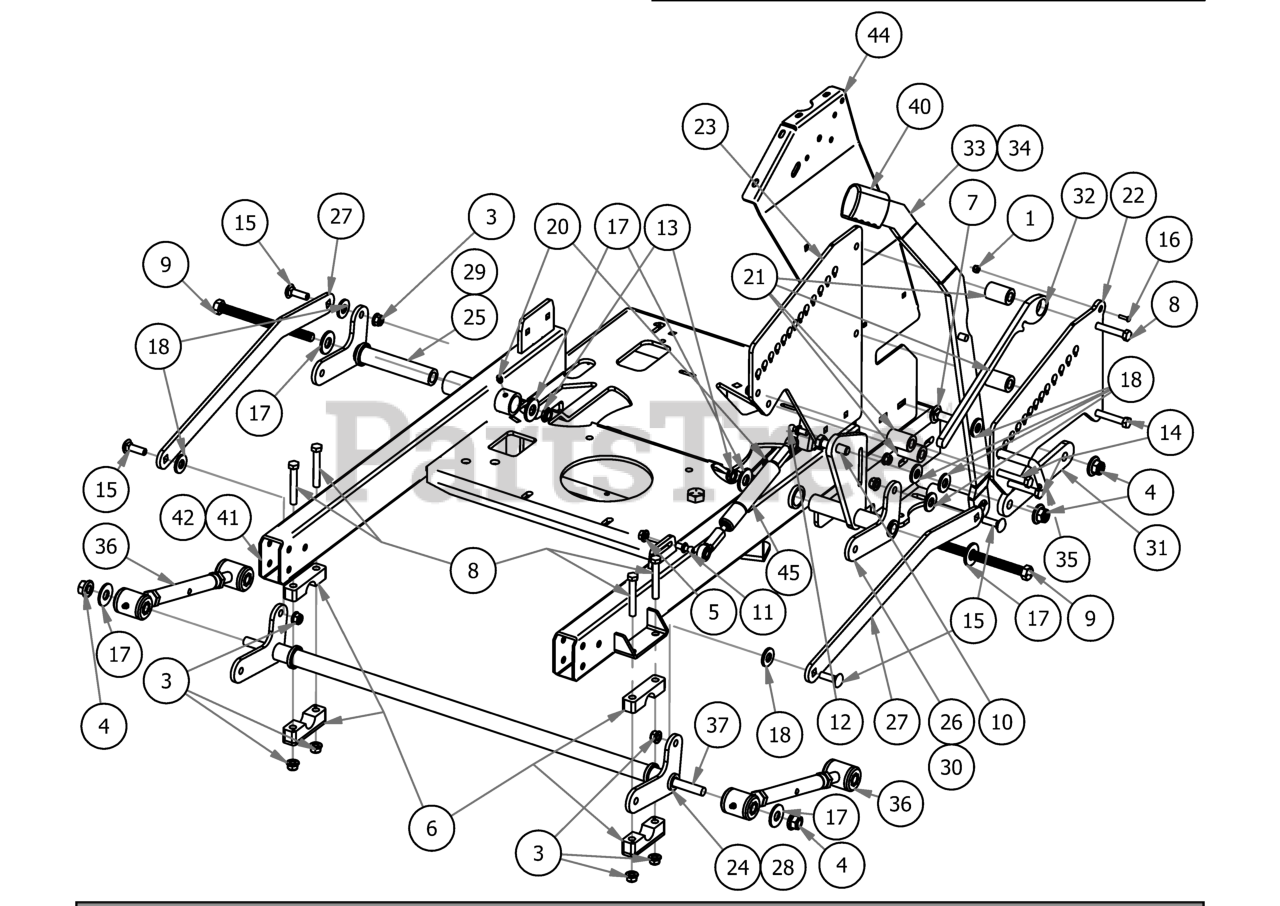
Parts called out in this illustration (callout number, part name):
1	10-24 Nylon Insert Locknut Zinc
2	3/8 Nylock Nut
3	3/8 Nylock Flange Nut
4	1/2-13 NYLON INSERT FLANGE LOCKNUT ZINC
5	5/16-18 Hex Flange Nuts Zinc w
6	Pillow Block Kit
7	1/2-13 X 1-1/2 CARRIAGE BOLT (GR.5) ZINC
8	3/8-16 x 2 1/2" Hex Bolt
9	1/2-13 x 6 1/2 Hex Bolt
10	1/2-13 x 1 3/4" GR5 Hex Bolt
11	10mm Damper Ball Stud-Steering
12	10mm Damper Ball Stud-XP Linkage
13	1/2-13 NYLON INSERT JAM LOCKNUT ZINC
14	3/8-16x3 grade 5 hex bolt
15	3/8-16 X 1-1/4 Carriage Bolt
16	10-24 X 5/8 BS C/S 18-8 SS
17	1/2 Flat Washer
18	.505 Nylon Spacer
19	Revolt Cotter Pin for 7/8" to 1" shank
20	1/4" Press in Grease Fitting
21	.502 ID X .750 OD X 1.500 Long Spacer
22	2019 Stand On Outer Adjustment Plate
23	2019 Stand On Inner Adjustment Plate
24	2019 Stand On Front Actuator Bar Weldment
25	2019 Stand On Actuator Bar Rear RH
26	2019 Stand On Actuator Bar Rear- LH
27	2019 Stand-on Actuator Linkage
28	2020 36 Stand On Front Actuator Bar Weldment
29	2020 36 Stand On Actuator Rear RH
30	2020 36 Actuator rear_LH
31	2019 Stand On Lever Secondary Linkage
32	2019 Stand on deck lever lock
33	2019 Stand On Lift Lever Weldment
34	2020 36 Stand On Lift Lever Weldment
35	Height Adj Pin
36	2018 Maverick Turnbuckle (Top Link) (36" ONLY)
37	2020 36 Stand On Turnbuckle Rod
38	Revolt Fuel Line Assembly
39	2019 REVOLT FUEL TANK
40	2019 Stand On Lift Grip
41	2019 Stand On Frame Weldment
42	2020 36 Stand On Frame Weldment
43	2019 Stand On Gas Tank Strap
44	2019 Podium Panel Left
45	200 lb Gas Spring- 54" Deck outlaw
